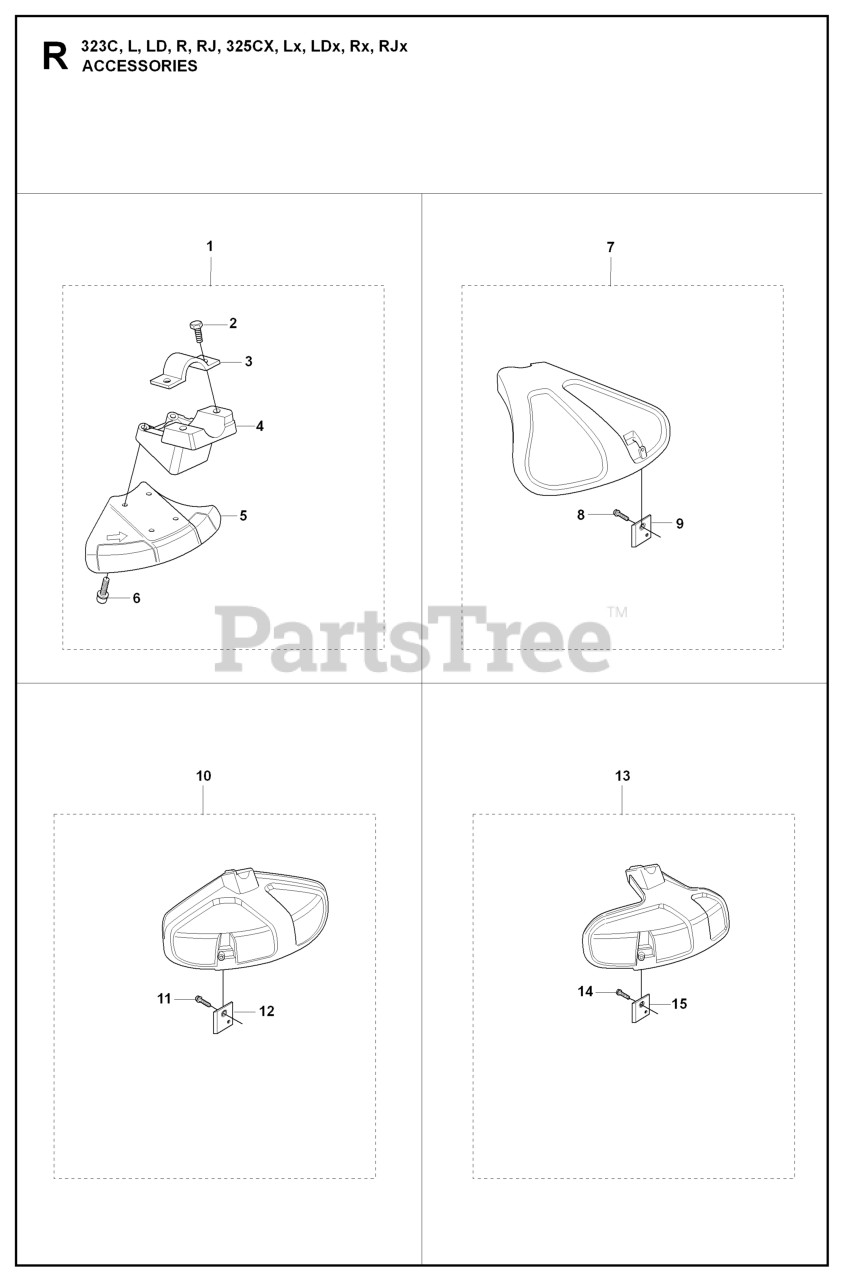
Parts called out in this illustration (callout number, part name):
1	TRIMMER GUARD ASSY
2	BOLT FLANGE - M6X20
3	CLAMP
5	BLADE GUARD
7	GRASS SHIELD
9	LINE CUTTER
10	GRASS SHIELD
12	LINE CUTTER
13	TRIMMER GUARD ASSEMBLY
15	LINE CUTTER
